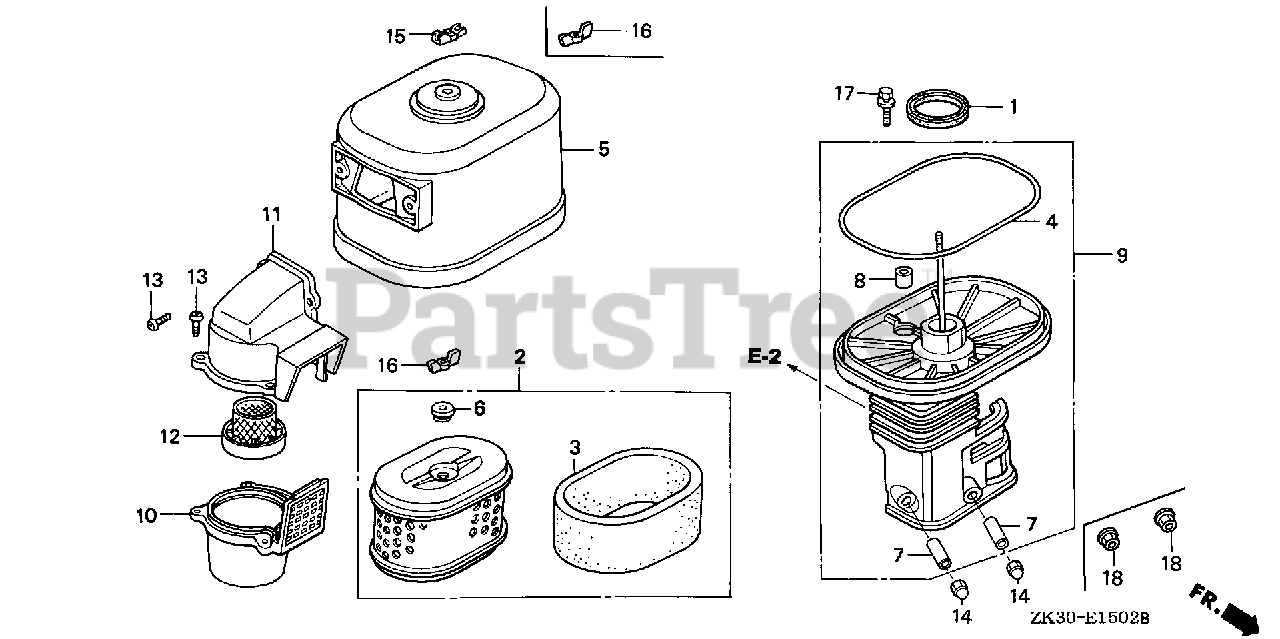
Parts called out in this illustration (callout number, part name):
1	GASKET, ELBOW
2	ELEMENT, AIR CLEANER
3	FILTER (OUTER)
4	SEAL, AIR CLEANER COVER
5	COVER, AIR CLEANER (CYCLONE)
6	GROMMET, AIR CLEANER
7	COLLAR, AIR CLEANER
8	COLLAR B, AIR CLEANER
9	ELBOW, AIR CLEANER
10	CASE, PRE AIR CLEANER
11	CAP, PRE AIR CLEANER
12	GUIDE, PRE AIR CLEANER
13	SCREW, PAN (5X16.5)
16	NUT, TOOL BOX SETTING
17	BOLT-WASHER (6X22)
18	NUT, FLANGE (6MM)
